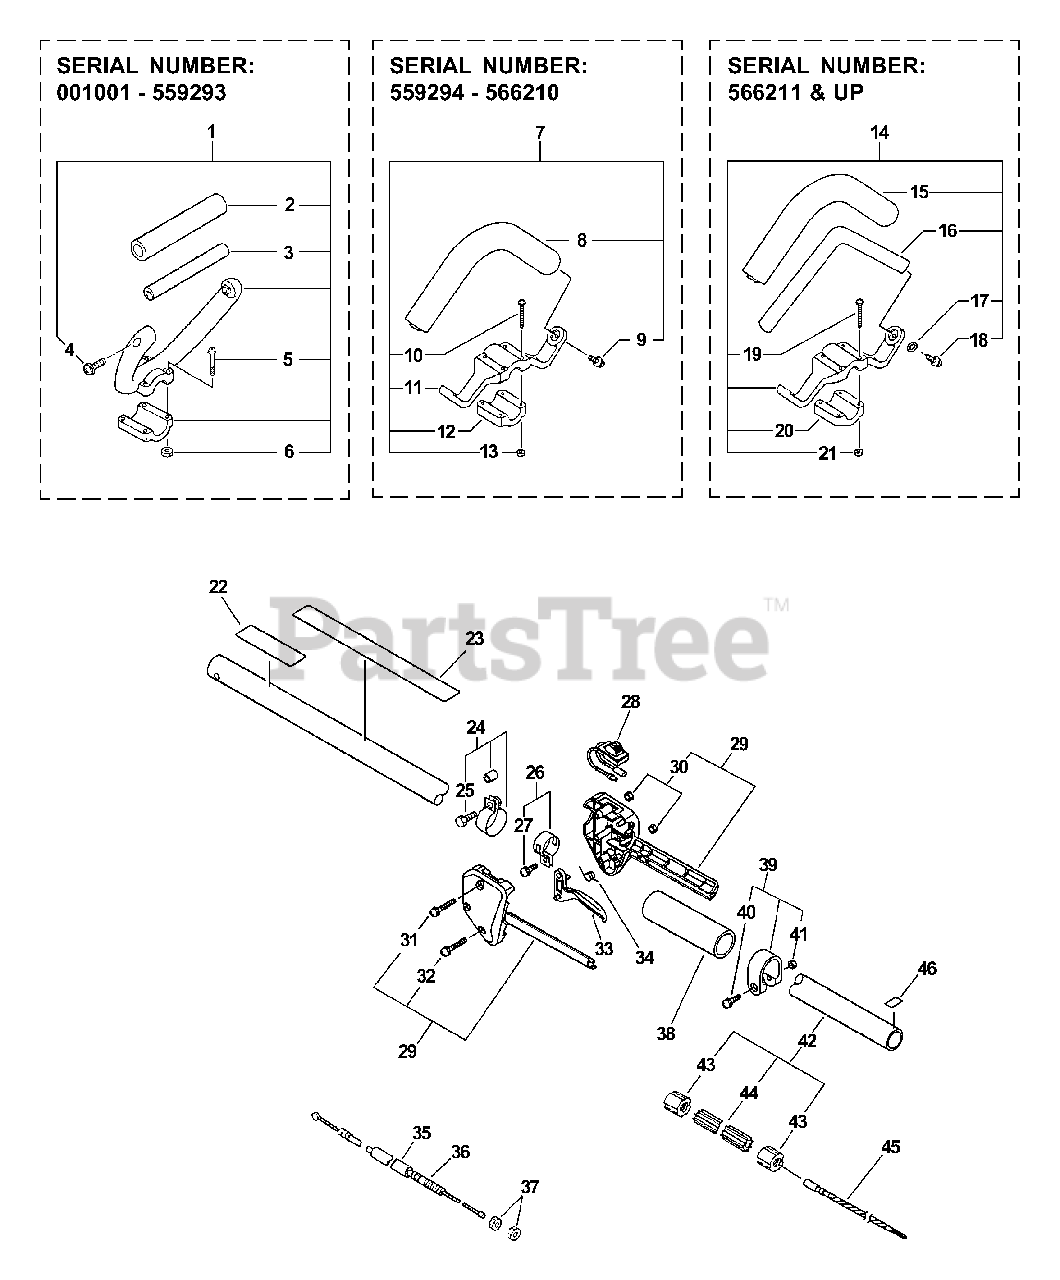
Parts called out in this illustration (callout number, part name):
1	LOOP HANDLE ASSY
2	GRIP, HANDLE
3	HANDLE
4	SCREW 5×30
5	SCREW 5×35
6	NUT M5
7	FRONT HANDLE ASSY
8	HANDLE
9	SCREW 5×14
10	SCREW 5×35
11	BRACKET, HANDLE
12	BRACKET, HANDLE - LOWER
13	NUT M5
14	HANDLE ASSY, FRONT
15	GRIP, HANDLE
16	HANDLE, SUPPORT
17	WASHER, FLAT 5.5×10×0.8
18	SCREW 5
19	SCREW 5×35
20	BRACKET, HANDLE - LOWER
21	NUT M5
22	LABEL, CAUTION
23	LABEL, CAUTION
24	HOOK
25	BOLT 5×18
26	CLAMP KIT
27	SCREW 5×14
28	IGNITION SWITCH ASSY
29	HANDLE KIT, CONTROL
30	NUT M5
31	SCREW 5×35
32	SCREW 5×25
33	TRIGGER, THROTTLE
34	SPRING, TORSION
35	TUBE
36	CABLE, THROTTLE
37	NUT M6
38	GRIP, HANDLE
39	CLAMP KIT
40	SCREW 5×28
41	NUT M5
42	MAIN PIPE ASSY 25×1500
44	LINER, FLEXIBLE 21.6×1420
45	DRIVESHAFT - FLEXIBLE L= 1522
46	LABEL - ALIGNMENT
